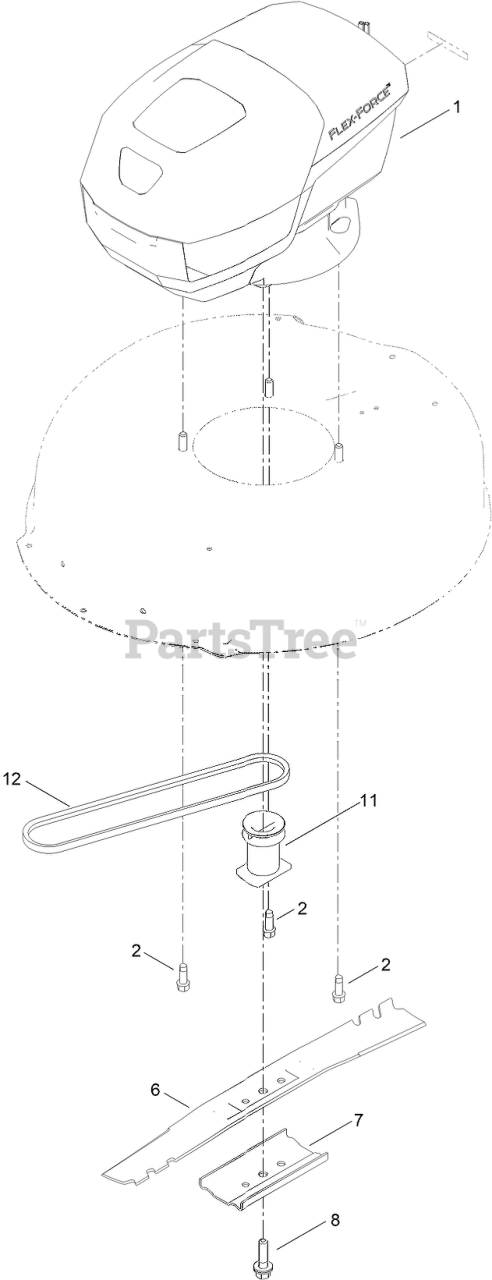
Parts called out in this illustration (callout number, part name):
1	MOTOR MODULE
2	SCREW-TAPTITE
6	BLADE-21IN (MULCH, HS)
7	SUPPORT-BLADE
8	BOLT-BLADE
11	DRIVER-BLADE
12	V-BELT
